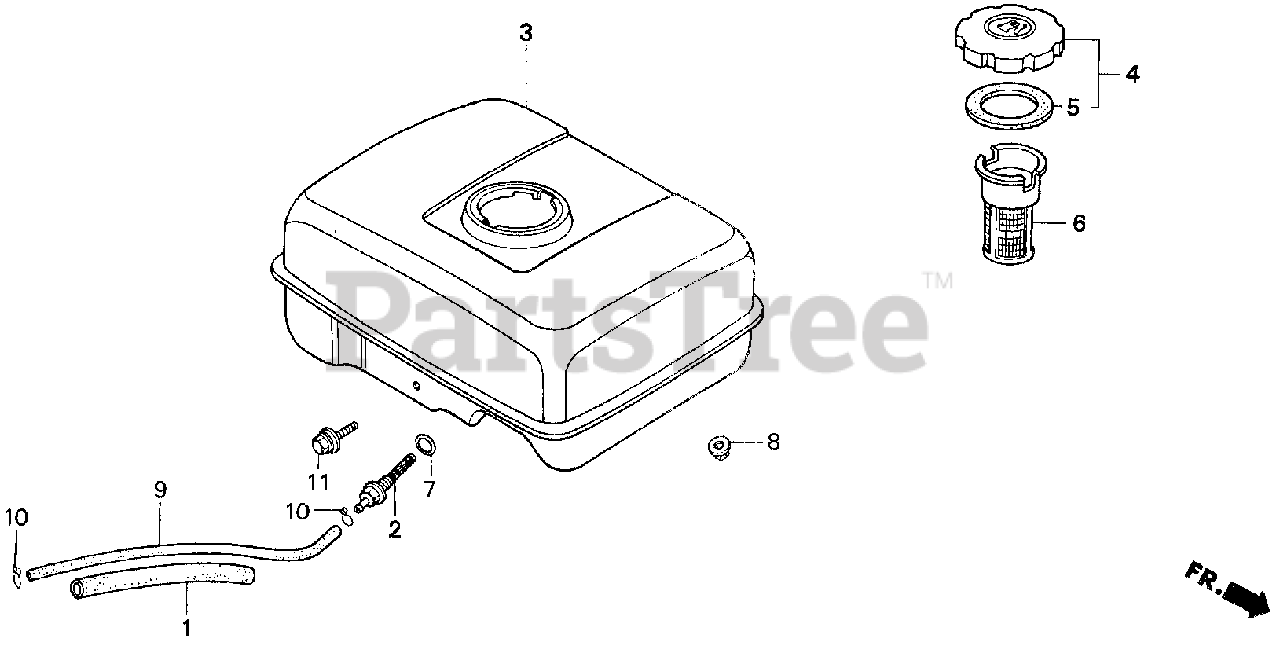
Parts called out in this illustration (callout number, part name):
1	RUBBER, SUPPORTER (107MM)
2	JOINT, FUEL TANK
3	TANK, FUEL *NH31* (MCKINLEY WHITE)
3	TANK, FUEL *NH1* (BLACK)
4	CAP, FUEL FILLER
5	GASKET, FUEL FILLER CAP
6	FILTER, FUEL
7	O-RING (13.5X1.5) (ARAI)
8	NUT, FLANGE (6MM)
9	BULK HOSE, FUEL (4.5X3000) (4.5X140)
10	CLIP, TUBE (B8)
11	BOLT, FLANGE (6X30)
